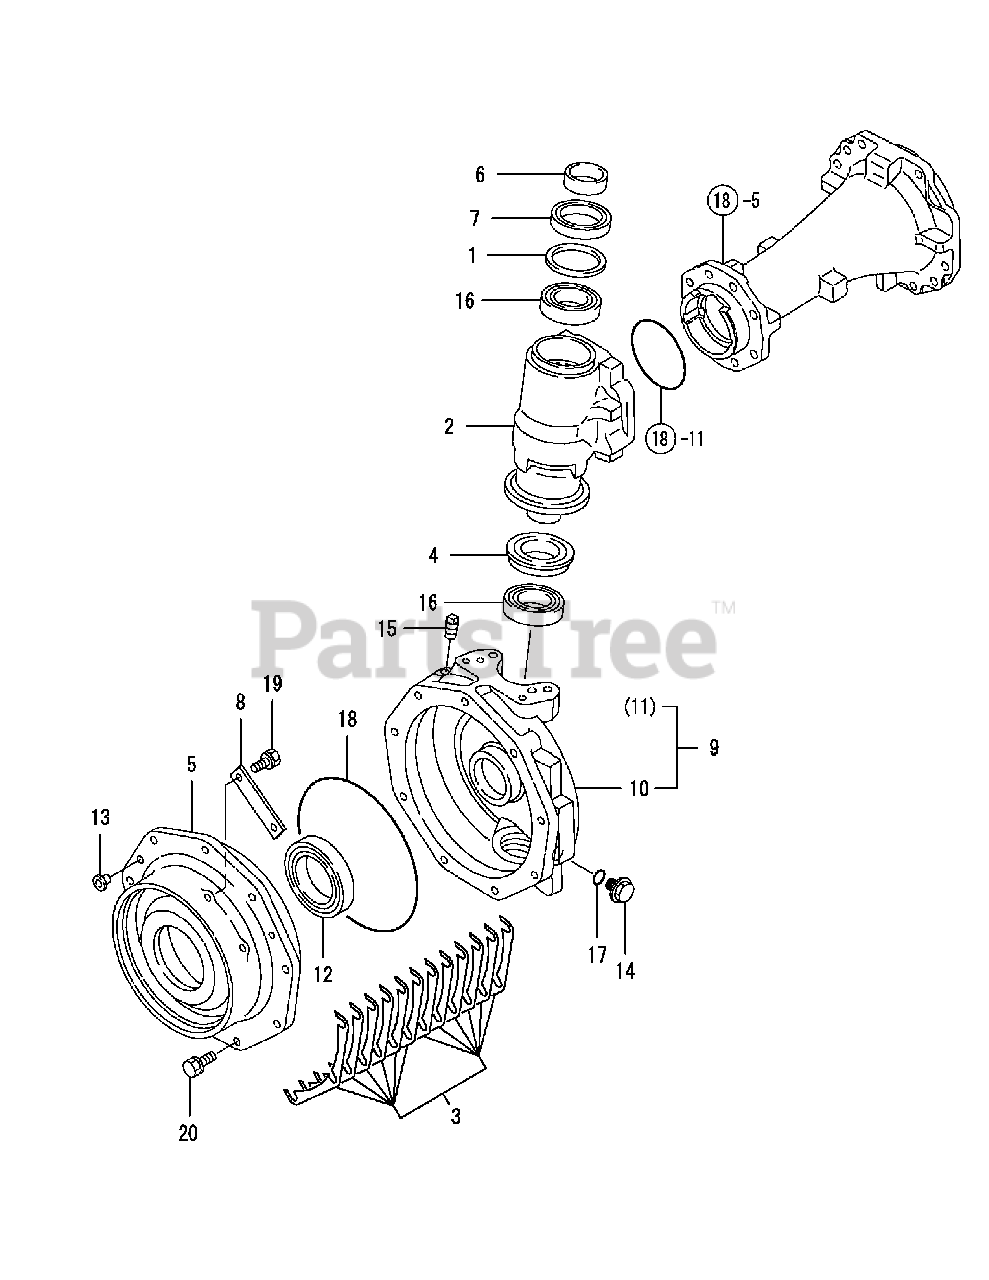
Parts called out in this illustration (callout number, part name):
2	CASE,SIDE GEAR
7	SEAL TC6Y 558514
8	SUPPORT,BEARING
9	BOX, FRONT GEAR
11	BOX R,FRONT GEAR
12	SEAL TC6Y 80 105 15
15	PLUG PT1/8,SCREW
17	O-RING 1A P-16.0
20	BOLT W/WASHER M10X25
